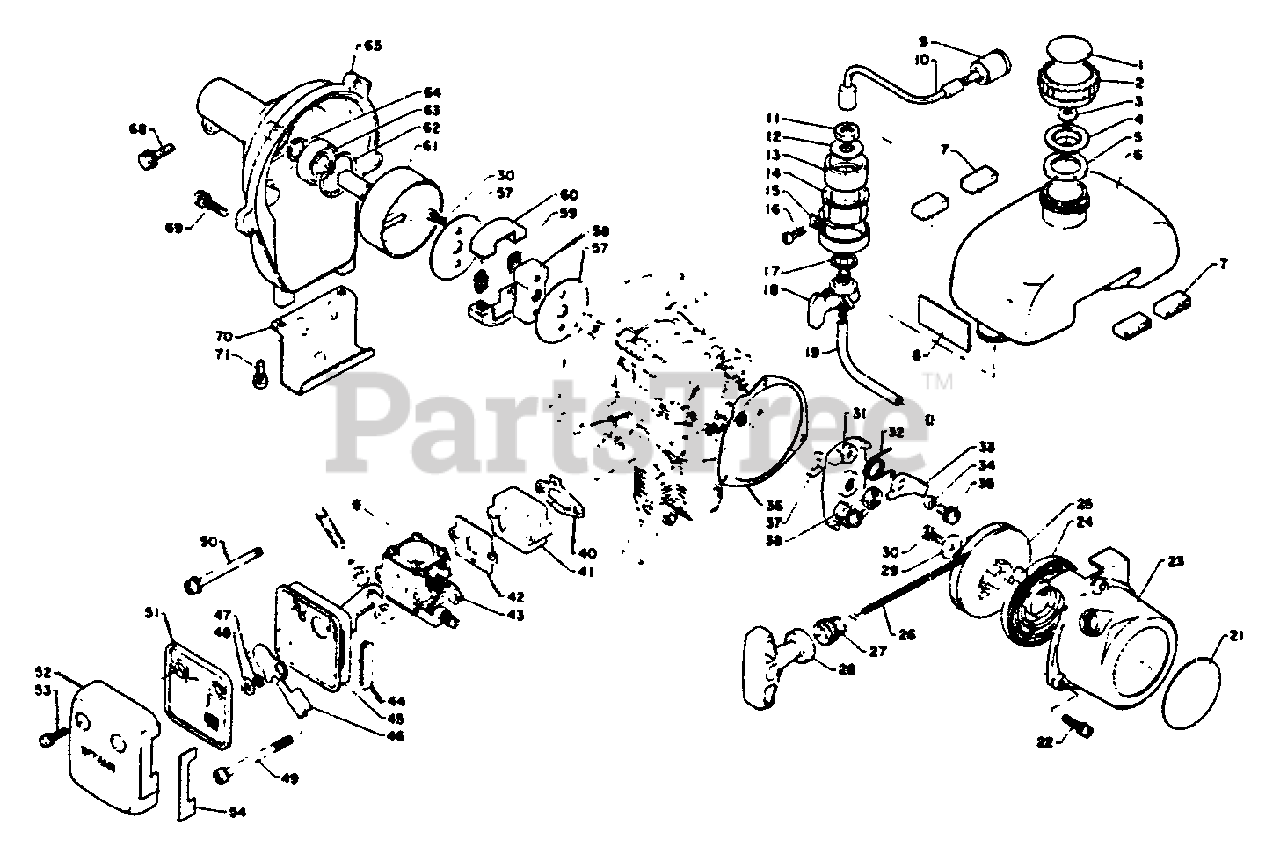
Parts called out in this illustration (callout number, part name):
1	LABEL - FUEL MIX
2	CAP
4	HOLDER, VENT
5	GASKET, CAP
6	TANK, FUEL
7	CUSHION, FUEL TANK
8	LABEL - FUEL VALVE
9	FILTER, FUEL
10	PIPE - FUEL
12	WASHER
13	SEAL
14	COLLAR
16	SCREW - 4X14
17	GASKET
18	FUEL VALVE ASSY
19	PIPE - 3X6X85 -- BLACK
21	LABEL - ECHO
22	SCREW - 4X18
23	CASE, STARTER
24	SPRING, REWIND
25	REEL, ROPE
26	ROPE, STARTER - 3X850
27	GUIDE, ROPE
28	GRIP, STARTER
30	SCREW - 4X10
31	CATCHER, PAWL
32	SPRING, RETURN
33	PAWL, STARTER
35	SCREW - 5X10
36	GASKET, STARTER
38	NUT - LEFT HAND
40	GASKET, INTAKE
41	INSULATOR, INTAKE
42	GASKET, INTAKE
43	CARBURETOR
45	CASE, AIR FILTER
46	SHUTTER, CHOKE
47	WASHER - 5
48	WASHER
49	SCREW - 5X57
50	SCREW - 5X57
51	FILTER, AIR
52	COVER, AIR FILTER
53	SCREW - 4X16
54	LABEL - CAUTION
57	PLATE, CLUTCH
58	HUB, CLUTCH
59	SPRING, CLUTCH
60	SHOE, CLUTCH
61	DRUM, CLUTCH
62	RING, RETAINING - 28
63	BEARING, BALL - 6001 DDU
64	RING, RETAINING - 12
65	CASE, FAN
68	BOLT - 5X20
69	SCREW - 5X20
70	BRACKET, CUSHION
71	SCREW - 5X12
